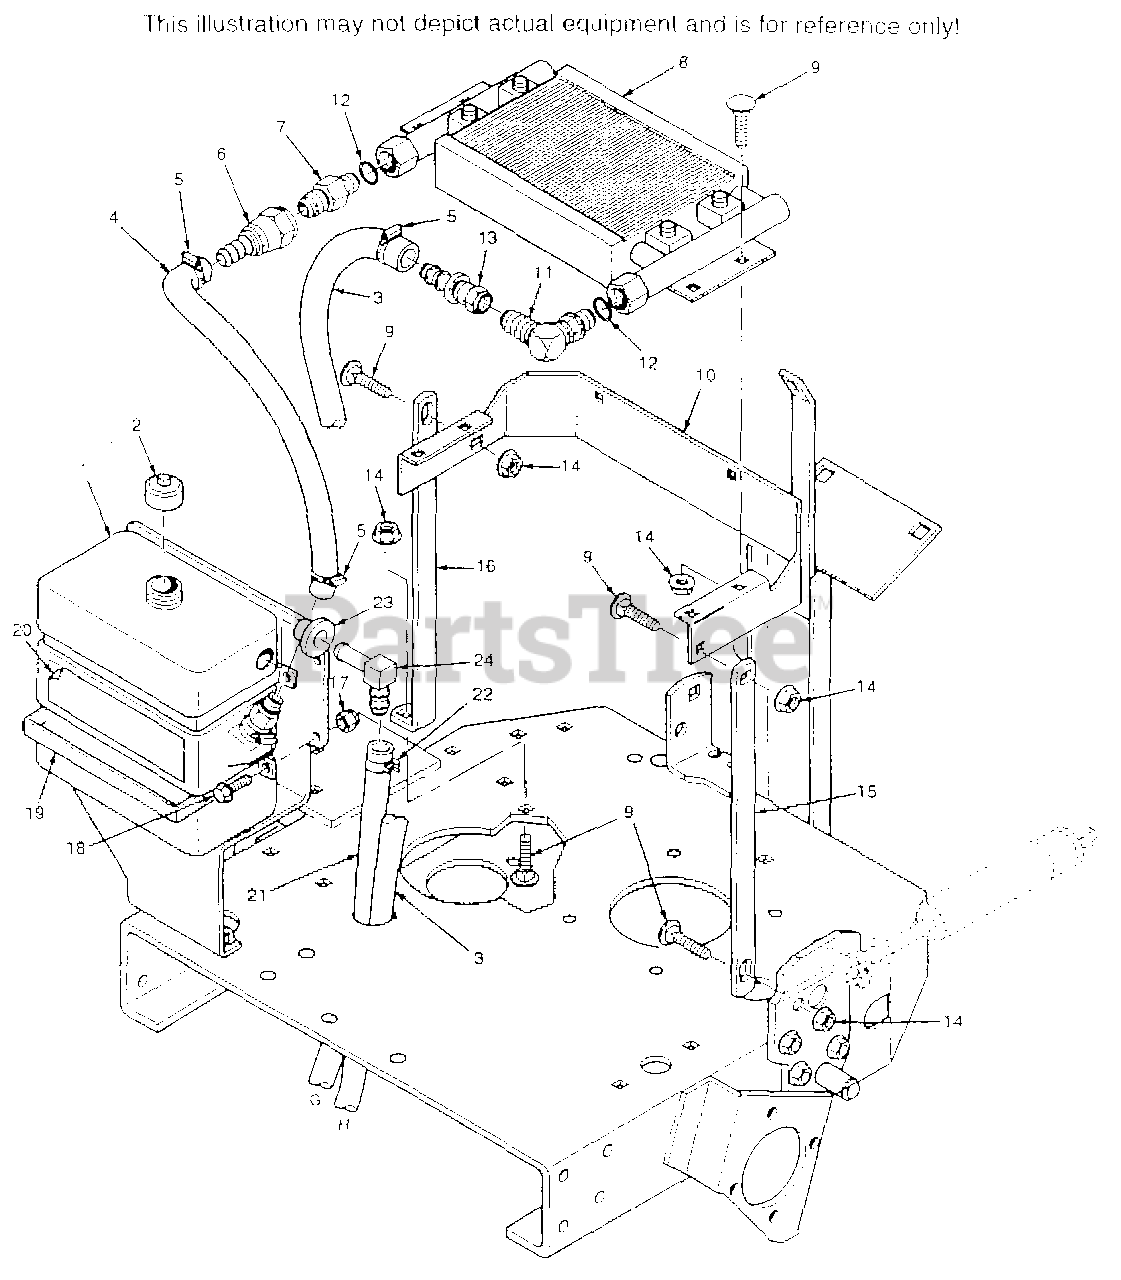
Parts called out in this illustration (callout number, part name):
1	TANK, HYDRAULIC W/DECAL
2	CAP, HYDRAULIC TANK
3	HOSE, PUMP TO OIL COOLER
4	HOSE, OIL COOLER TO TANK
5	CLAMP, HOSE
6	COUPLING, FLARE SWIVEL
7	TUBE, UNION
8	OIL COOLER ASSEMBLY
10	BRACKET, OIL COOLER
11	ELBOW, 90 DEGREES
12	O-RING
13	COUPLING FLARE SWIVEL
14	SERR. FL. HEX HEAD NUT, 5/16-18
15	BRACE, L.H. COOLER SUPPORT
16	BRACE, R.H. COOLER SUPPORT
18	SERR. FL. HEX HEAD CPSCR, 1/4-20 X 3/4
19	STRAP, OIL TANK
20	DECAL, SCAG
21	HOSE
23	BUSHING
24	90 DEGREE ELBOW
